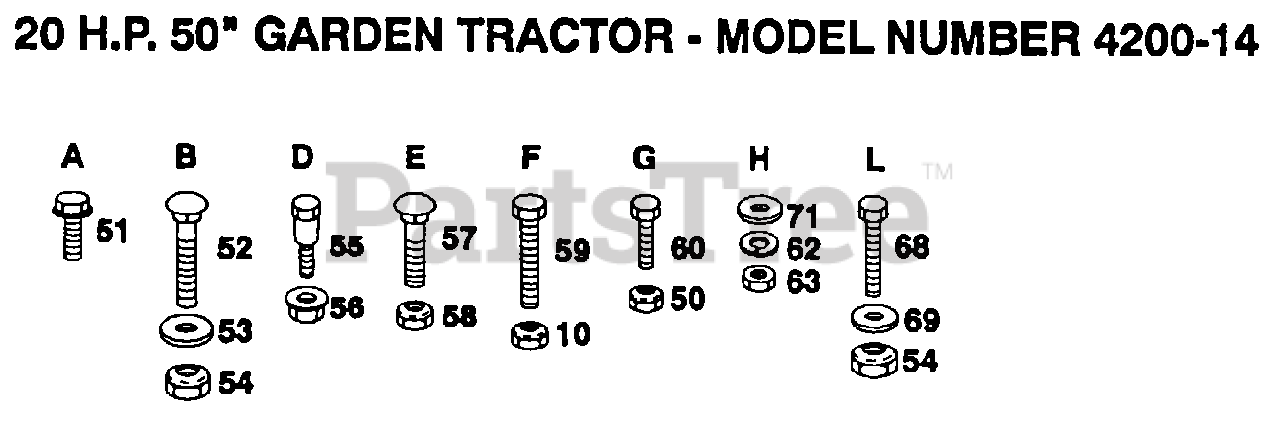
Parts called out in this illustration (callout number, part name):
51	SCREW LT
52	BOLT
53	WASHER
55	SHOULDER BOLT T
56	NUT T
57	BOLT
58	LOCKNUT
59	BOLT
60	BOLT
68	BOLT
69	WASHER M
71	WASHER PM
